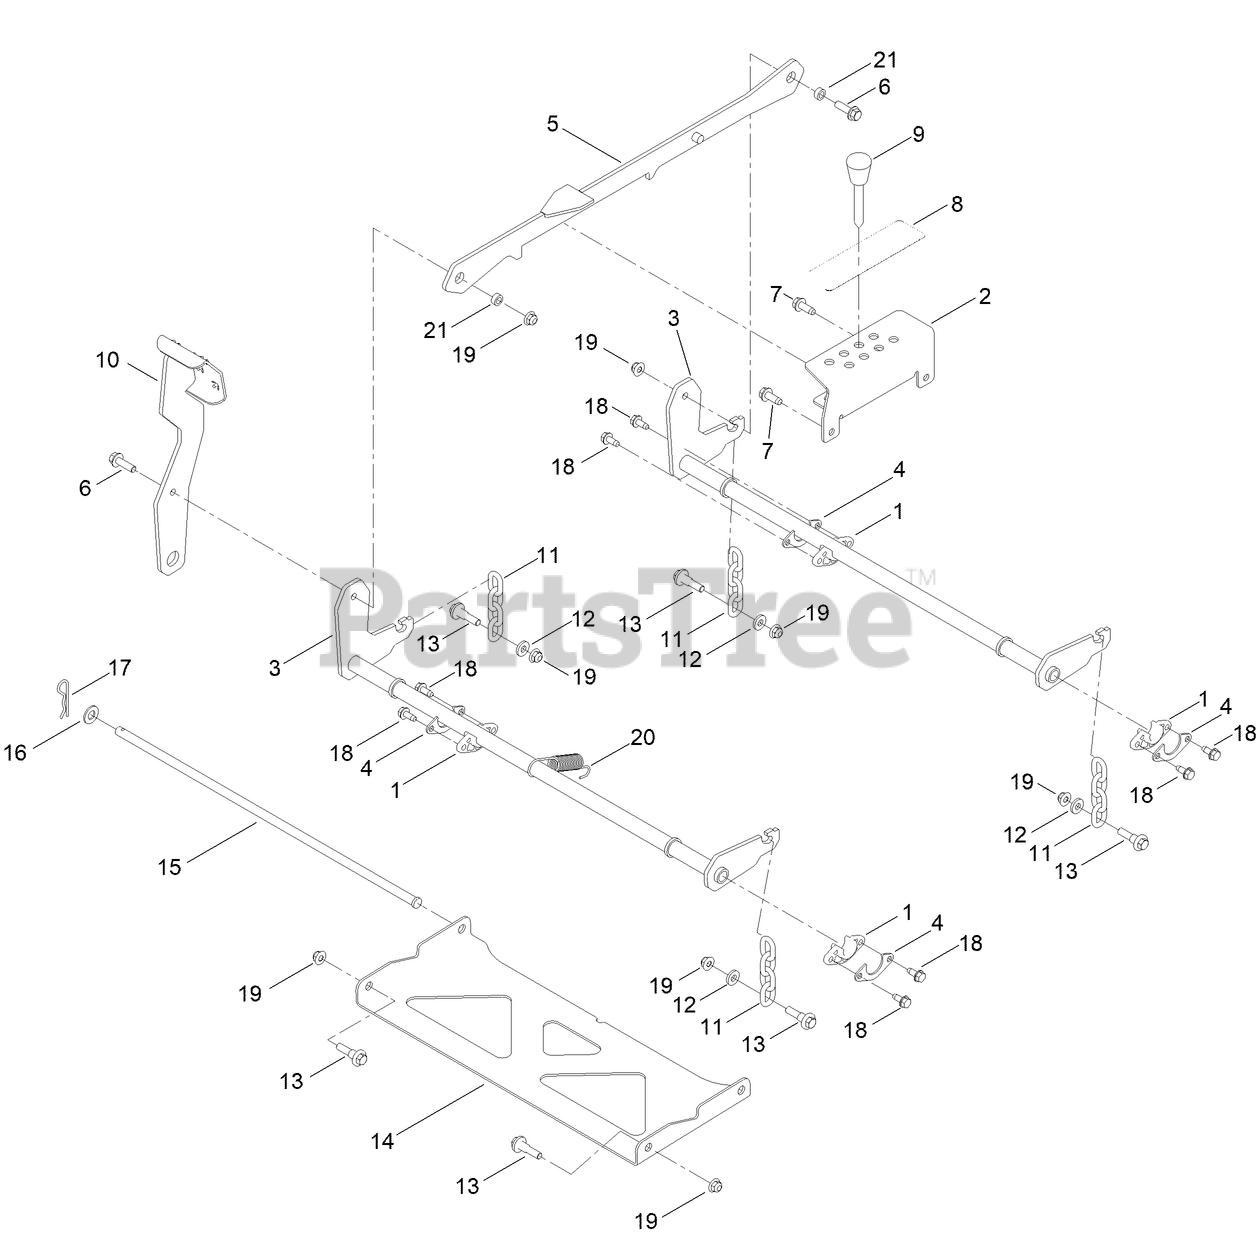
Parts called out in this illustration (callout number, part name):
1	BEARING-FLANGE
2	BRACKET-HOC
3	PIVOT ASM-DECKLIFT [RED]
4	GUSSET-DECK LIFT
5	LINK ASM-HOC [RED]
6	SCREW-HHF
7	SCREW-HWH
8	DECAL-HOC, TC
9	HOC PIN ASM
10	PEDAL ASM [RED]
11	CHAIN-DECKLIFT, 4-LINK
12	SPACER-HUB, BLOWER
13	BOLT-SHOULDER
14	PAN-DECK PIVOT
15	PIN-DECK
16	WASHER-FLAT
17	PIN-HAIR
18	SCREW-HWHTF
19	NUT-HF, NI
20	SPRING-EXTENSION
21	SPACER
